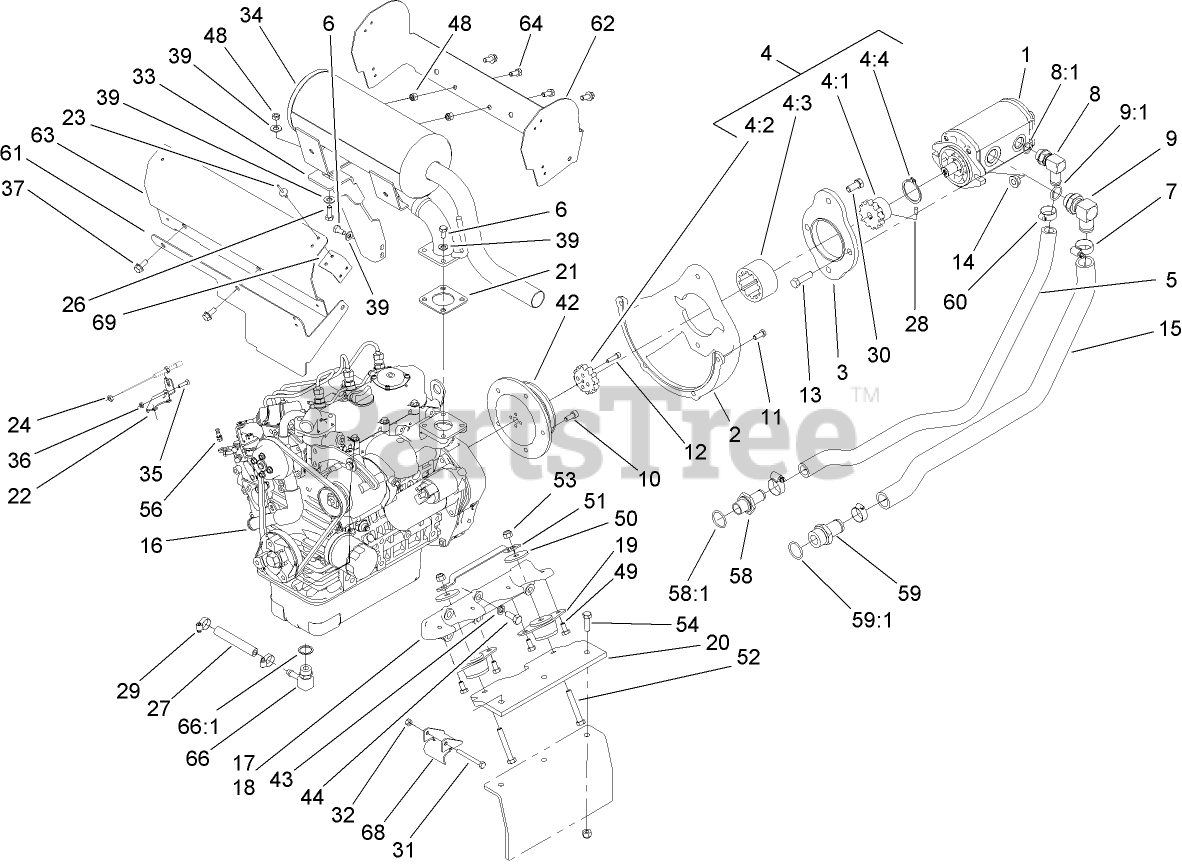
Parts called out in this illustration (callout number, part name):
1	PUMP-HYD
2	PUMP-MOUNT
3	PLATE-MOUNT, PUMP
4	COUPLING ASM
4:1	HUB-COUPLING
4:2	SLEEVE-HUB
4:3	SLEEVE-COUPLING
4:4	RING-SNAP, COUPLING
5	HOSE-FORMED, SUCTION
6	BOLT
7	CLAMP-HOSE
8	FITTING
8:1	O-RING
9	FITTING-HYD, 90 DEG
9:1	O-RING
10	SCREW-CAP, HSH
11	SCREW-HH
12	SCREW-HSH
13	SCREW-HH
14	NUT-HF
15	HOSE-FORMED, SUCTION
16	ENGINE-KUBOTA
17	MOUNT-ENGINE, LH
18	MOUNT-ENGINE, RH
19	MOUNT-ENGINE
20	PLATE-MOUNT, ENGINE
21	GASKET-MUFFLER
22	BRACKET-SUPPORT, THROTTLE
23	RIVET
24	NUT-JAM
26	SCREW-HH
27	HOSE-DRAIN
28	SCREW-SET, HSH
29	CLAMP-HOSE
30	SCREW-HH
31	SCREW-HH
32	NUT-LOCK, CONE
33	SUPPORT-MUFFLER
34	MUFFLER ASM
35	SCREW-TORX
36	NUT-HEX
37	SCREW-HHF
39	WASHER-PLAIN
42	PULLEY
43	WASHER-LOCK, SPRING
44	SCREW-HH
48	NUT-LOCK, CONE
49	SCREW-HH
50	WASHER-REBOUND
51	STRAP-REBOUND
52	SCREW-HH
53	NUT-LOCK, NI
54	SCREW-HH
56	SWIVEL-STOP, CABLE
58	FITTING-HOSE, BARBED
58:1	O-RING
59	FITTING-STR
59:1	O-RING
60	CLAMP-HOSE
61	PLATE-BAFFLE, LOWER
62	PLATE-BAFFLE
63	PLATE-BAFFLE, MUFFLER
64	SCREW-HH
66	FITTING-BARBED-90
66:1	WASHER-SEAL, BONDED
68	GUIDE-CABLE
69	BRACKET-SHIELD
